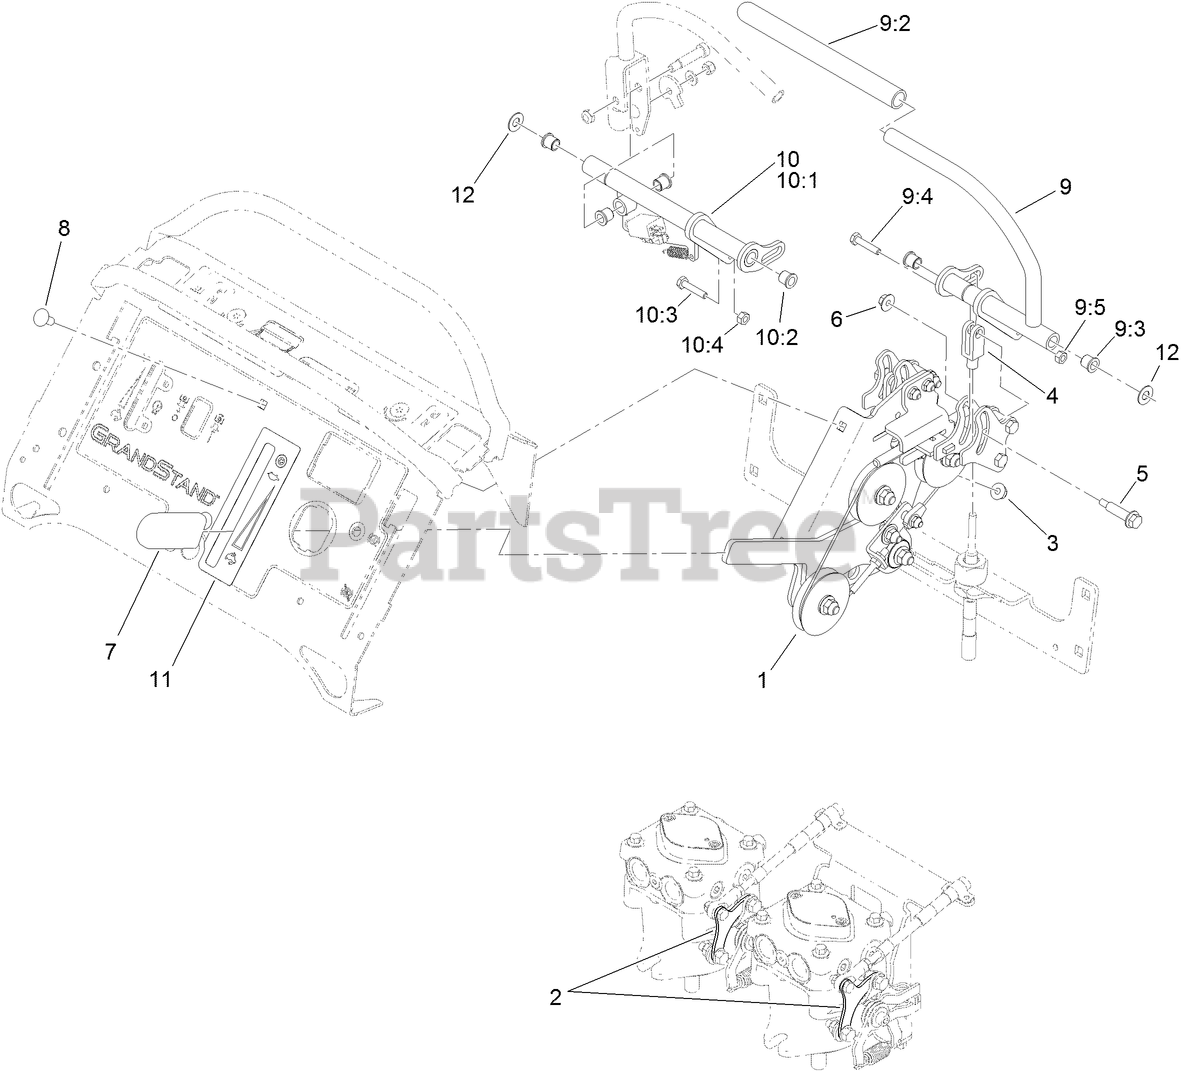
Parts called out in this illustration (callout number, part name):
1	SPEED CONTROL ASM
2	ARM-CONTROL, PUMP
3	NUT-HF, NI
4	YOKE-FEMALE
5	SCREW-SHOULDER, HHF
6	NUT-HF
8	BOLT-CARR
9	LH MOTION LEVER ASM
9:3	BEARING
9:4	SCREW-HH
9:5	NUT-HEX
10	RH MOTION TUBE ASM
10:1	TUBE ASM
10:2	BEARING
10:3	SCREW-HH
10:4	NUT-HEX
11	DECAL-SPEED
12	WASHER-PLAIN
